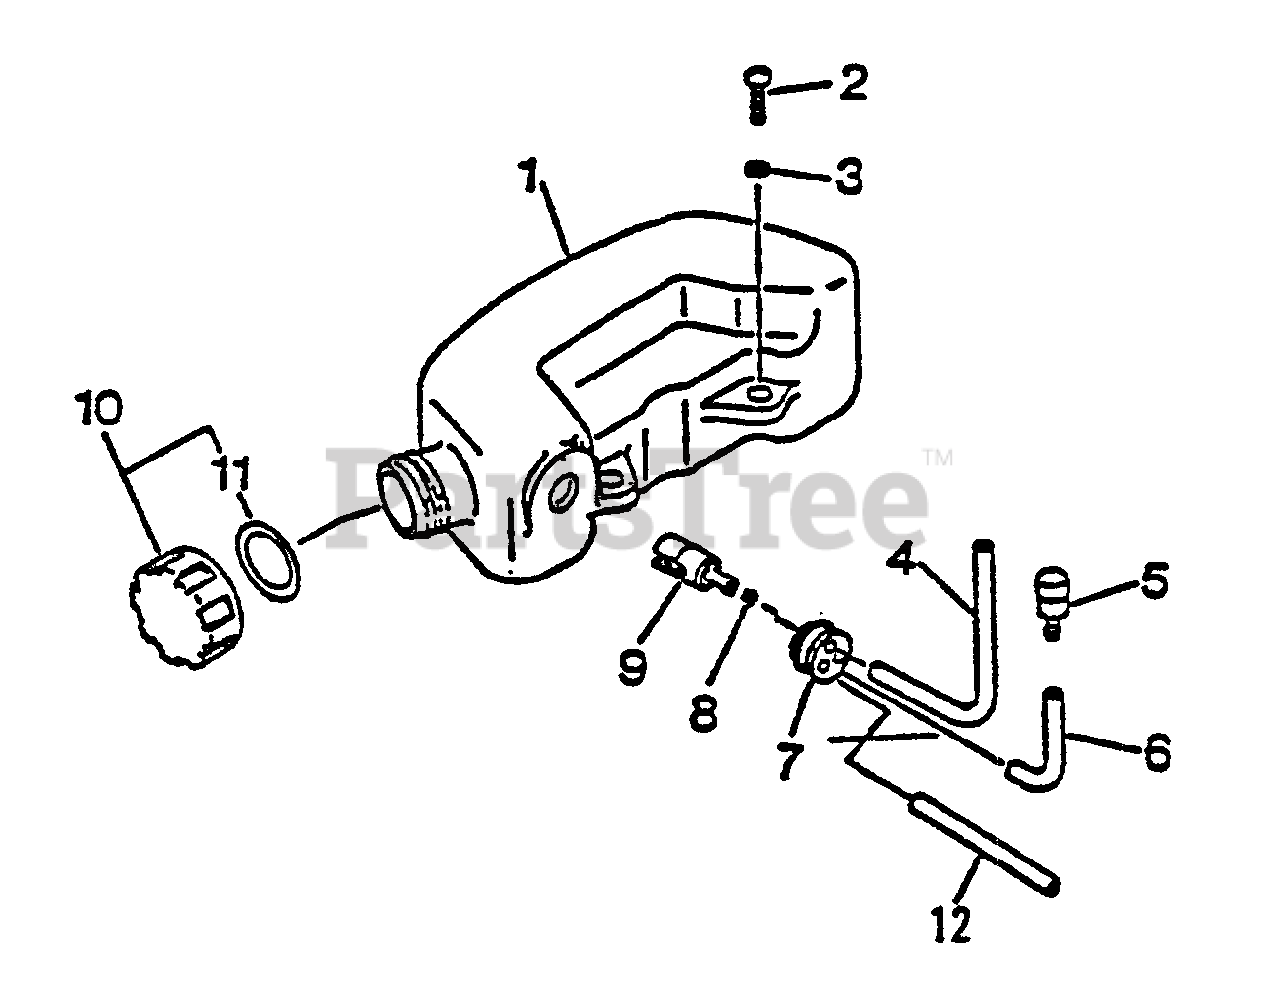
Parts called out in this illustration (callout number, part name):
1	TANK, FUEL
2	SCREW - 5X16
3	WASHER - 5
4	PIPE - 3X5X195 -- BLACK
5	VENT, FUEL TANK
6	PIPE - 3X6X70 -- CLEAR
7	GROMMET
8	CLIP - 6
9	FILTER, FUEL
10	CAP ASSY
11	GASKET, CAP
12	PIPE - 3X6X110 -- CLEAR
